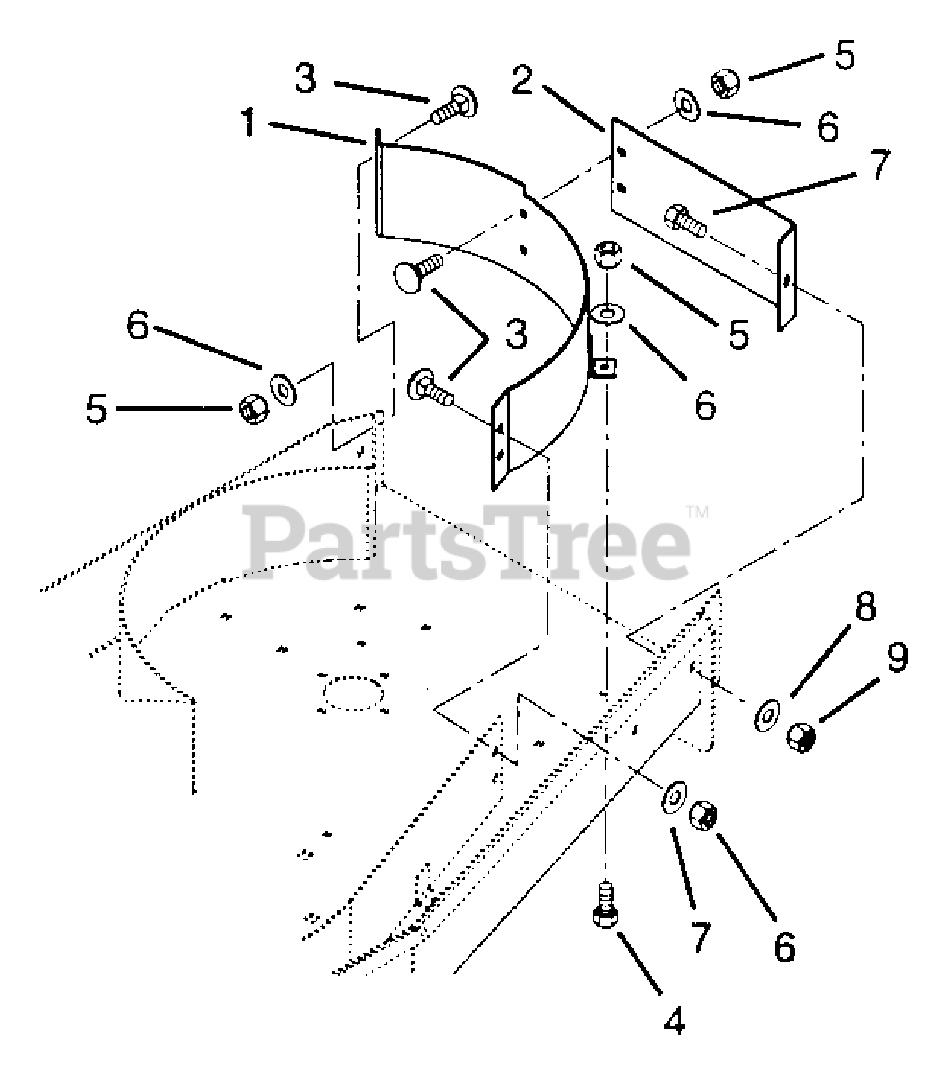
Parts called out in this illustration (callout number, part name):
1	Baffle, Weldment End
2	Baffle, End
3	Bolt, Round Head Square Shank .31-18 x 1.00
4	Bolt, Hex, .31-18 x 1.00 Grade 5
5	Nut, Locking Nylon .31-18
6	Washer, Flat Steel .344 x .688 x .065
7	Bolt, Hex .38-16 x .75 Grade 5
8	Washer, Flat Steel .38 x .875 x .083
9	Nut, Locking Nylon .38-16
